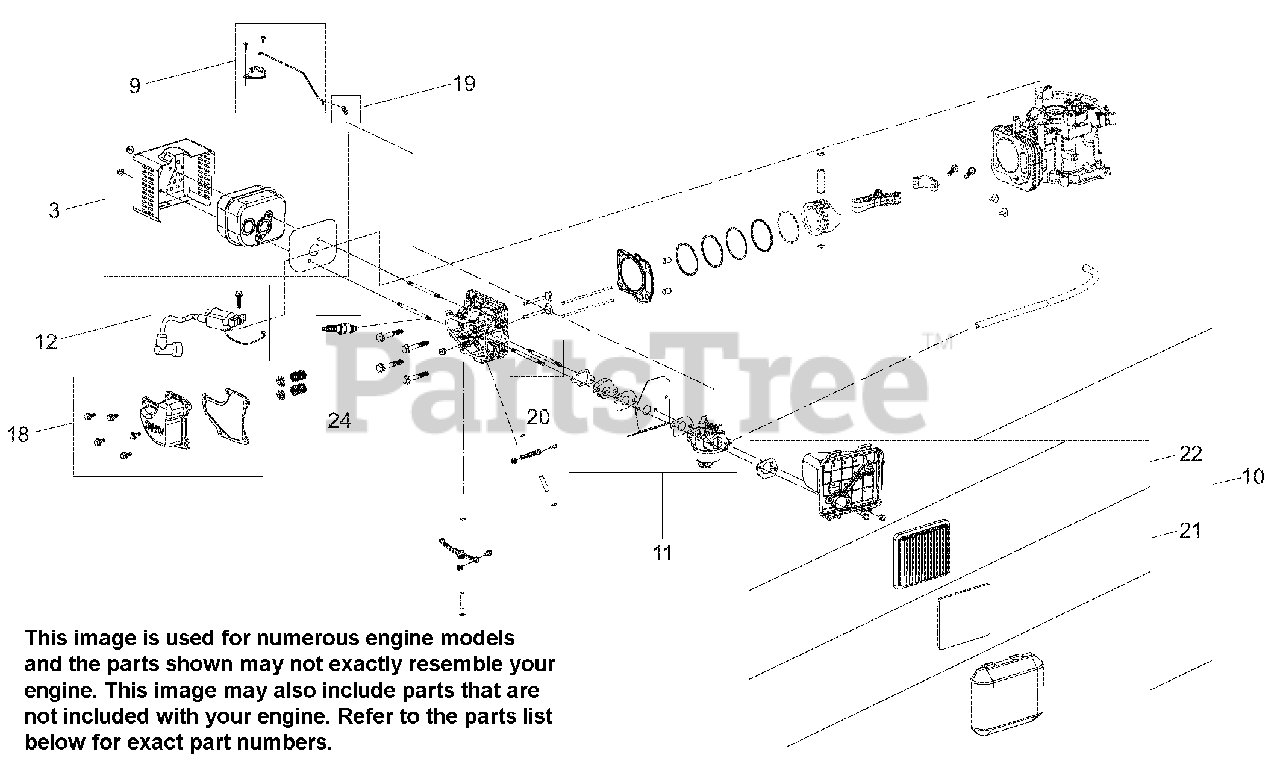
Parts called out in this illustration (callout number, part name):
1	KIT, AIR VANE CHOKE - SVC
2	KIT, GOVERNOR ARM - SVC
3	KIT, MUFFLER AND SHIELD - SVC
4	FLYWHEEL AND FAN KIT - RECOIL START
5	KIT BRAKE ASSEMBLY - RECOIL
6	KIT, E-START BRAKE ASM - SVC
7	KIT, ARIENS STYLE - SVC
8	KIT, FLYWHEEL SHIELD - SVC
9	KIT, THERMAL CHOKE CONTROL-SVC
10	KIT, AIR CLEANER ASM - SVC
11	KIT, CARBURETOR COMPLETE - SVC
12	KIT, IGNITION COIL - SVC
13	KIT, SEAL AND GASKET - SVC
14	KIT, FLYWHEEL AND FAN - SVC
16	KIT, STARTER - SVC
17	KIT, WIRE HARNESS - SVC
18	KIT, VALVE COVER - SVC
19	LOCK, THROTTLE - SVC
20	STUD, INTAKE - SVC
21	ELEMENT, AIR CLEANER
22	FILTER, AIR - LONCIN 160CC
23	KIT, FUEL LINE W/FILTER - SVC
24	SPARK PLUG, LONCIN 160CC
25	DIPSTICK, OIL - SVC
26	CAP, FUEL - SVC
27	ASM, FUEL TANK W/HARDWARE
28	KIT, RECOIL - SVC
29	ENGINE, SERVICE, AC SERIES
29	ENGINE,SERVICE,AC SERIES,ELEC
